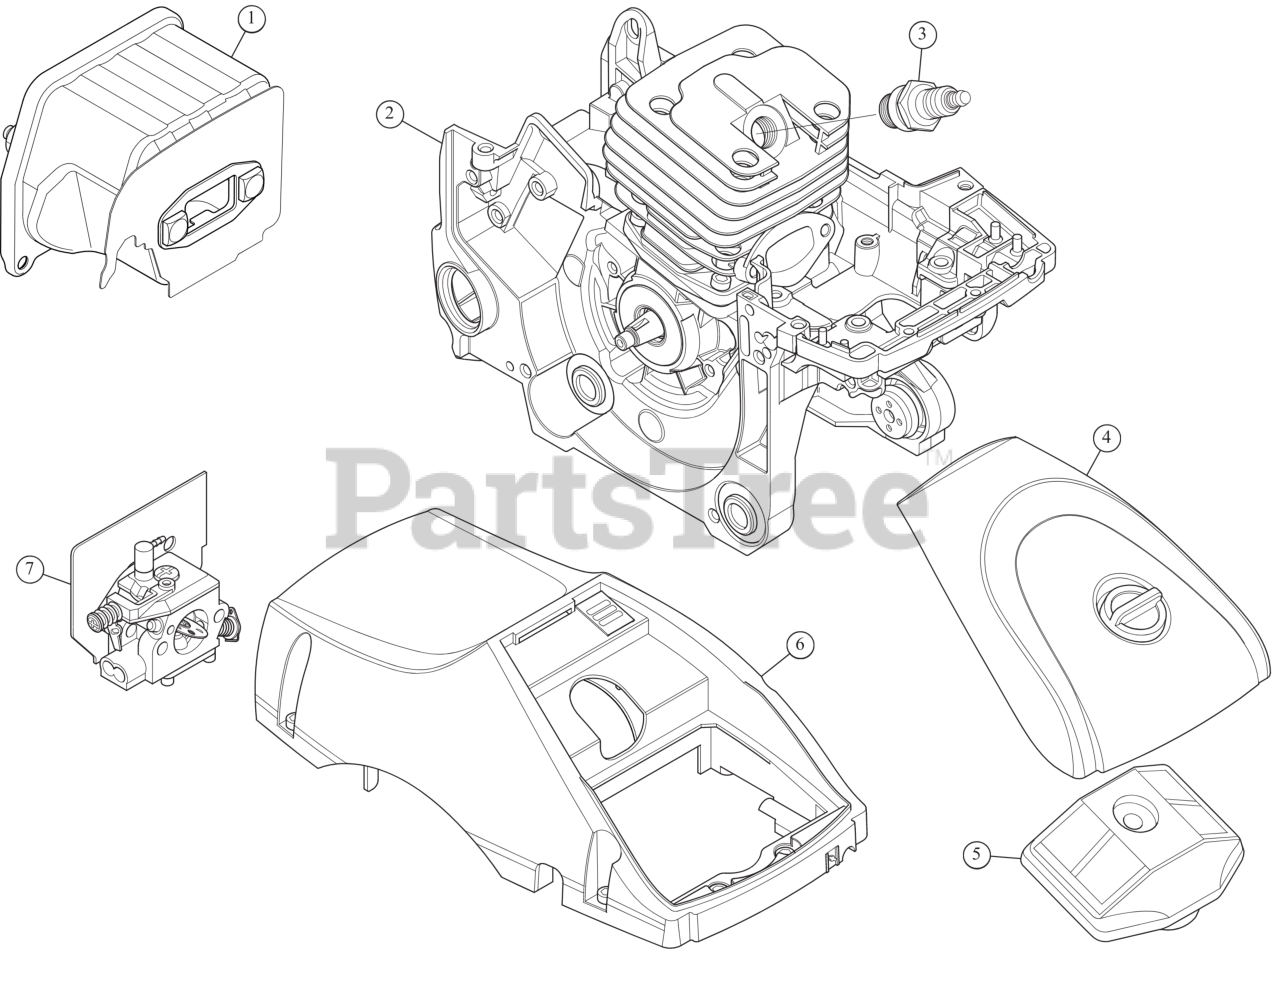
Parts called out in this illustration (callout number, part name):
1	MUFFLER ASSEMBLY
2	SHORTBLOCK 46CC
3	SPARK PLUG QCJ6Y
4	AIR FILTER COVER ASSEMBLY
5	AIR FILTER W/SEAL
6	COVER
7	CARBURATOR
